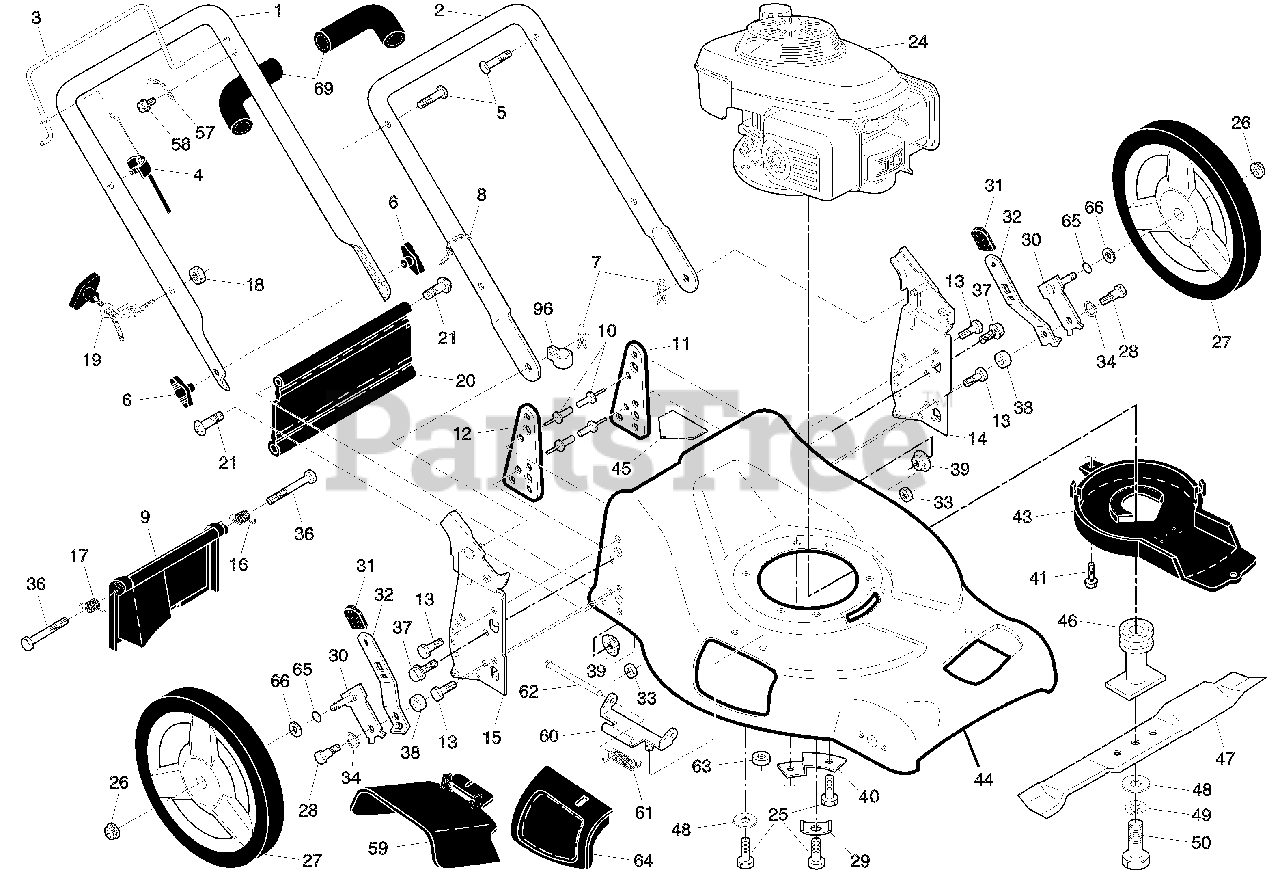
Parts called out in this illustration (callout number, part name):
1	Upper Handle
2	Lower Handle
3	Control Bar
4	Engine Zone Control Cable
5	Handle Bolt
6	Handle Knob
7	Hairpin Cotter
8	Wire Tie
9	Rear Door Assembly
11	Support Bracket, LH
12	Support Bracket, RH
13	Screw 1/4-20 x 5/8
14	Handle Bracket Assembly, LH
15	Handle Bracket Assembly, RH
16	Spring, Rear Door, LH
17	Spring, Rear Door, RH
18	Keps Locknut 1/4-20
19	Rope Guide
20	Rear Skirt
21	Screw, Hinge 1/4-20 x 1/2
25	Hex Head Thread Rolling Screw 3/8-16 x 1-1/8
26	Hex Flange Nut
27	Wheel & Tire Assembly, Rear, 12"
28	Shoulder Bolt 5/16-18 x .33
29	Washer, Engine, Zinc-Plated
30	Axle Arm Assembly, Rear
31	Selector Knob
32	Selector Spring
33	Nut, Hex 5/16-18
34	Washer, Curved, Cyindrical
37	Thread Cutting Screw w/Sems 5/16-18 x 3/4
39	Nut, Hex, Flangelock 5/16-18
40	Mounting Bracket, Debris Shield
43	Debris Shield
44	Kit, Lawn Mower Housing
45	Danger Decal
46	Blade Adapter / Pulley
47	Blade, 21"
48	Hardened Washer
49	Helical Washer
50	Hex Head Machine Screw 3/8-24 x 1-3/8 Grade 8
57	Upstop Bracket
59	Discharge Defl ector
60	Hinge Bracket
63	Nut, Hex
64	Mulcher Door
66	Washer, Flat 1/2
69	Grip, Foam
96	Clip, Cable
